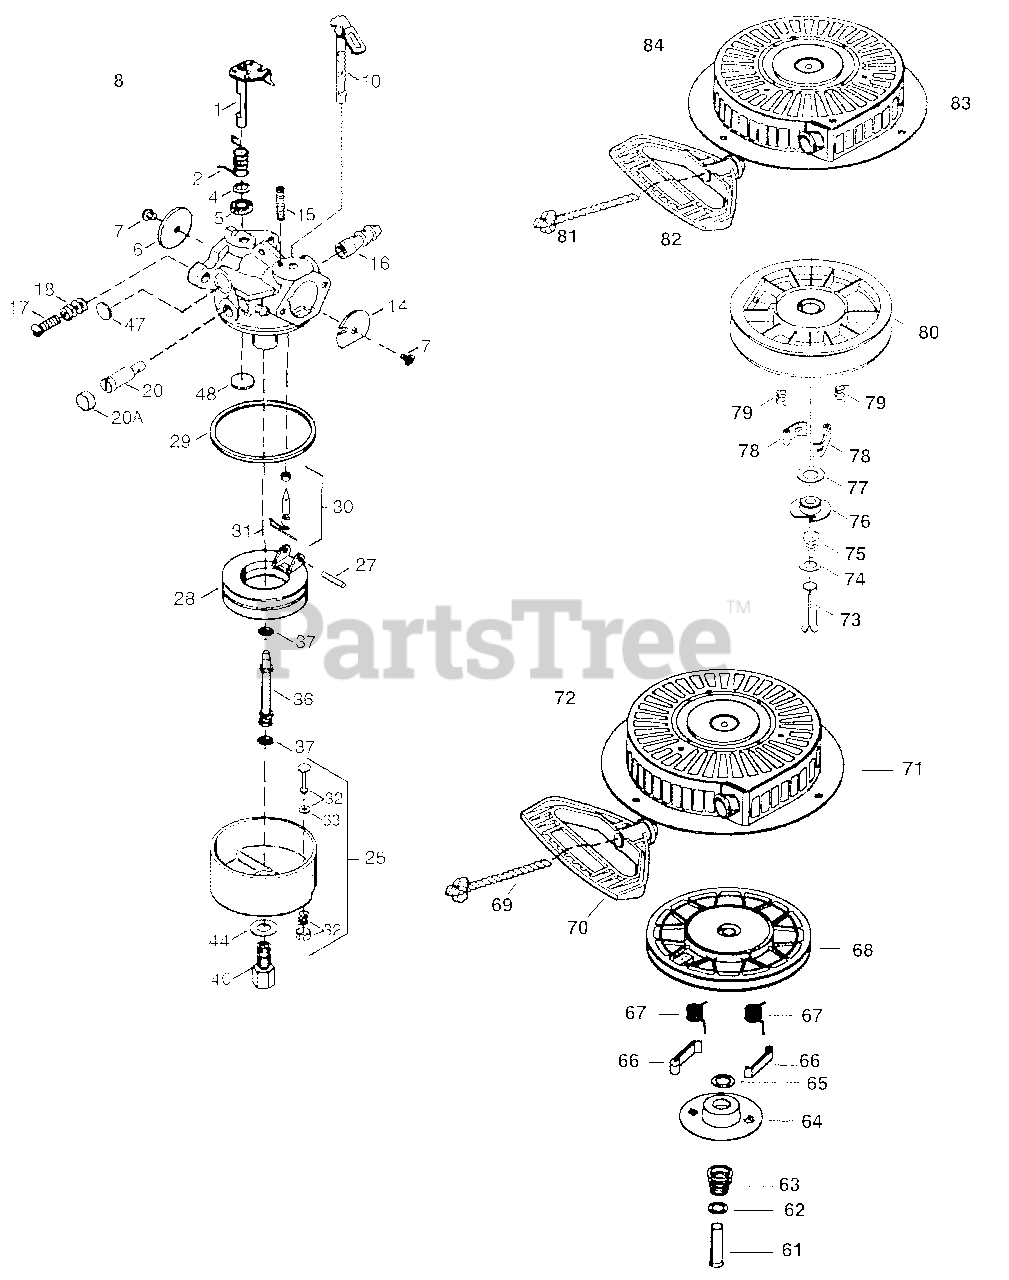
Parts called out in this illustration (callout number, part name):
1	Throttle Shaft & Lever Ass'y
2	Throttle Return Spring
4	Dust Seal Washer
5	Dust Seal (Throttle)
6	Throttle Shutter
7	Shutter Screw
8	Carburetor Ass'y
10	Choke Shaft & Lever Ass'y
14	Choke Shutter
15	Choke Positioning Spring
16	Fuel Fitting
17	Throttle Crack/Idle Speed Screw
18	Tension Spring
20	Idle Restrictor Screw
20A	Idle Restrictor Screw Cap
25	Float Bowl
27	Float Shaft
28	Float
29	Float Bowl "O" Ring
30	Inlet Needle, Seat & Clip
31	Spring Clip
32	Bowl Drain Ass'y
33	Drain Plunger Gasket
36	Main Nozzle Tube
37	Main Nozzle Tube "O" Ring
40	High Speed Bowl Nut
44	Bowl Nut Washer
47	Welch Plug, Idle Mixture Well
48	Welch Plug, Atmospheric Vent
61	Spring Pin
63	Brake Spring
66	Starter Dog
67	Dog Spring
68	Pulley & Rewind Spring Ass'y
69	Starter Rope (98")
70	Mitten Grip Starter Handle
71	Starter Housing Ass'y
72	Rewind Starter Ass'y
73	Spring Pin,
75	Brake Spring
78	Starter Dog
79	Dog Spring
80	Pulley & Rewind Spring Ass'y
81	Starter Rope (98")
82	Mitten Grip Starter Handle
83	Starter Housing Ass'y
84	Rewind Starter Ass'y
